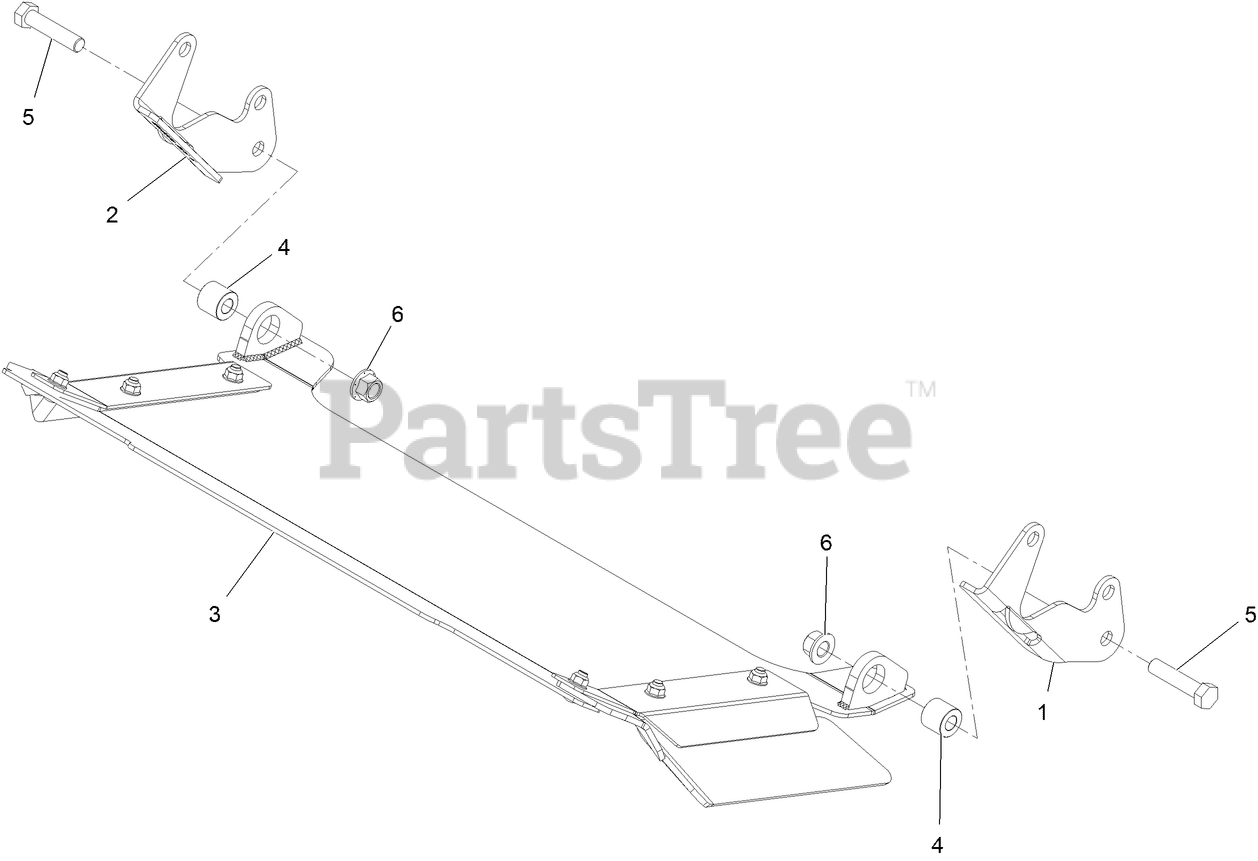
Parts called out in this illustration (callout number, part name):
1	BRACKET-DISCHARGE MOUNT, LH
2	BRACKET-DISCHARGE MOUNT, RH
3	DISCHARGE TUNNEL ASM
4	BUSHING-SLEEVE
5	SCREW-HH
6	NUT-LOCK
